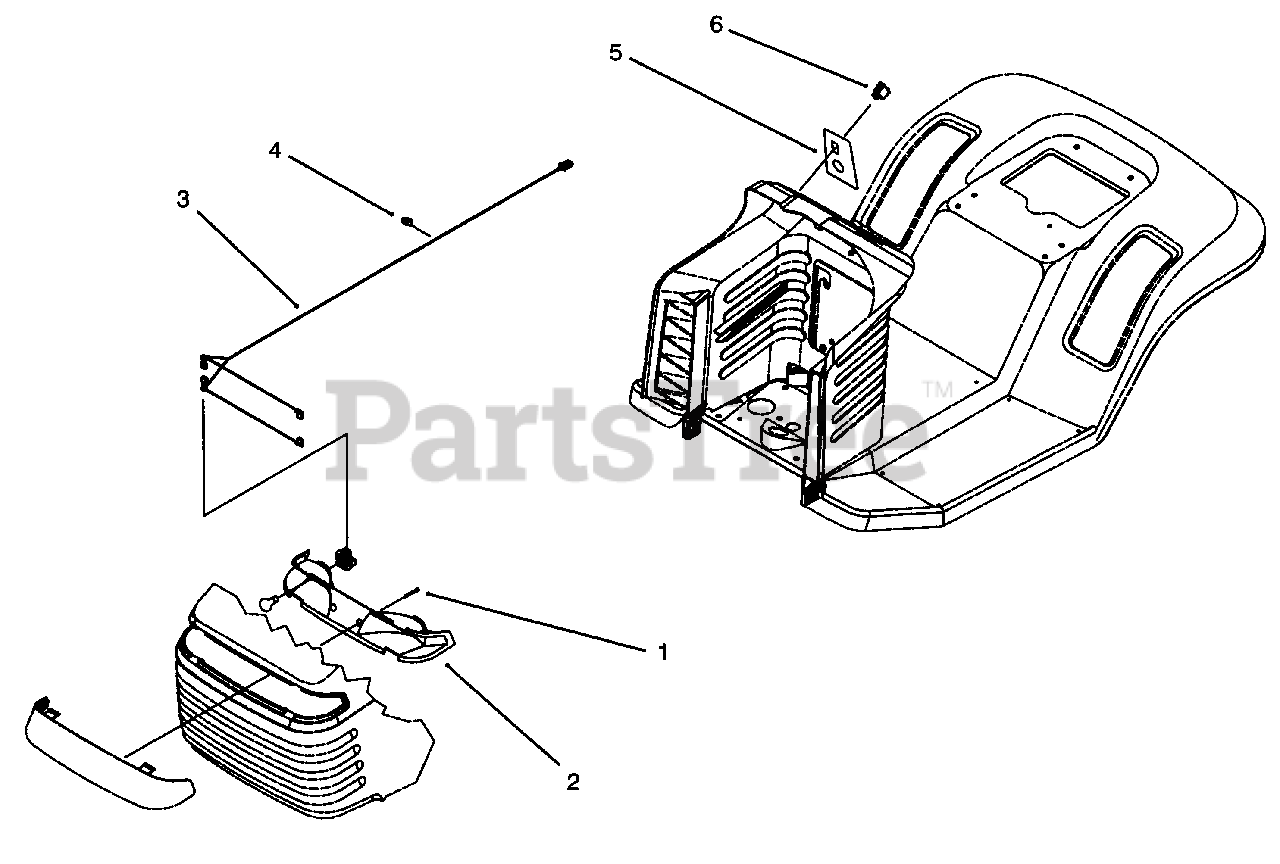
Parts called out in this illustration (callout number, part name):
1	Screw-Plastite
2	Reflector & Lamp Ass'y
3	Harness-Light Wire
4	Clip-Wire Retainer
5	Decal-Ignition/Lights (Model No. 71180 & 71191 Only)
6	Switch-Micro
